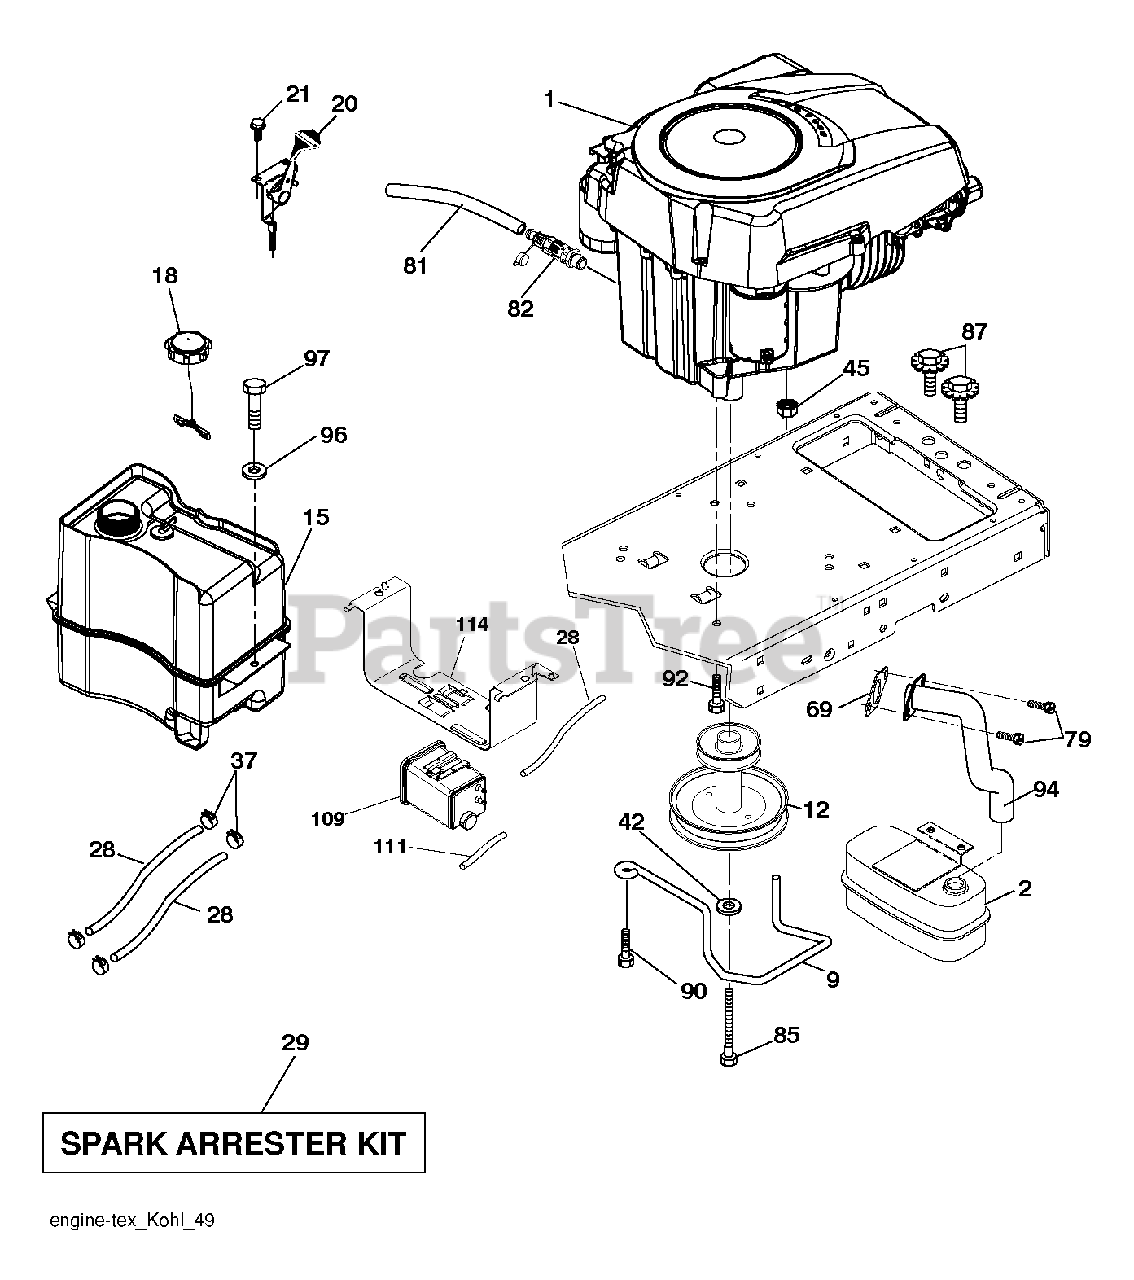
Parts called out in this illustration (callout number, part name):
9	KEEPER.BELT.ENGINE.4.2
21	SCREW.#10 X 0.750.BOS THREAD
29	ARRESTER SPARK (OPTIONAL)
37	HOSE CLAMP
42	LOCKWASHER
79	SCREW.SOCKET HD.5/16-1
81	TUBE, DRAIN OIL ASM.
82	VALUE.OIL.DRAIN
87	BOLT, 5/16-18 X 1 3/4
90	SCREW 3/8-16X1
92	SCREW 3/8-16X1
97	SCREW HEXWSHR 1/4-20X3/4
109	CANNISTER, CARBON
